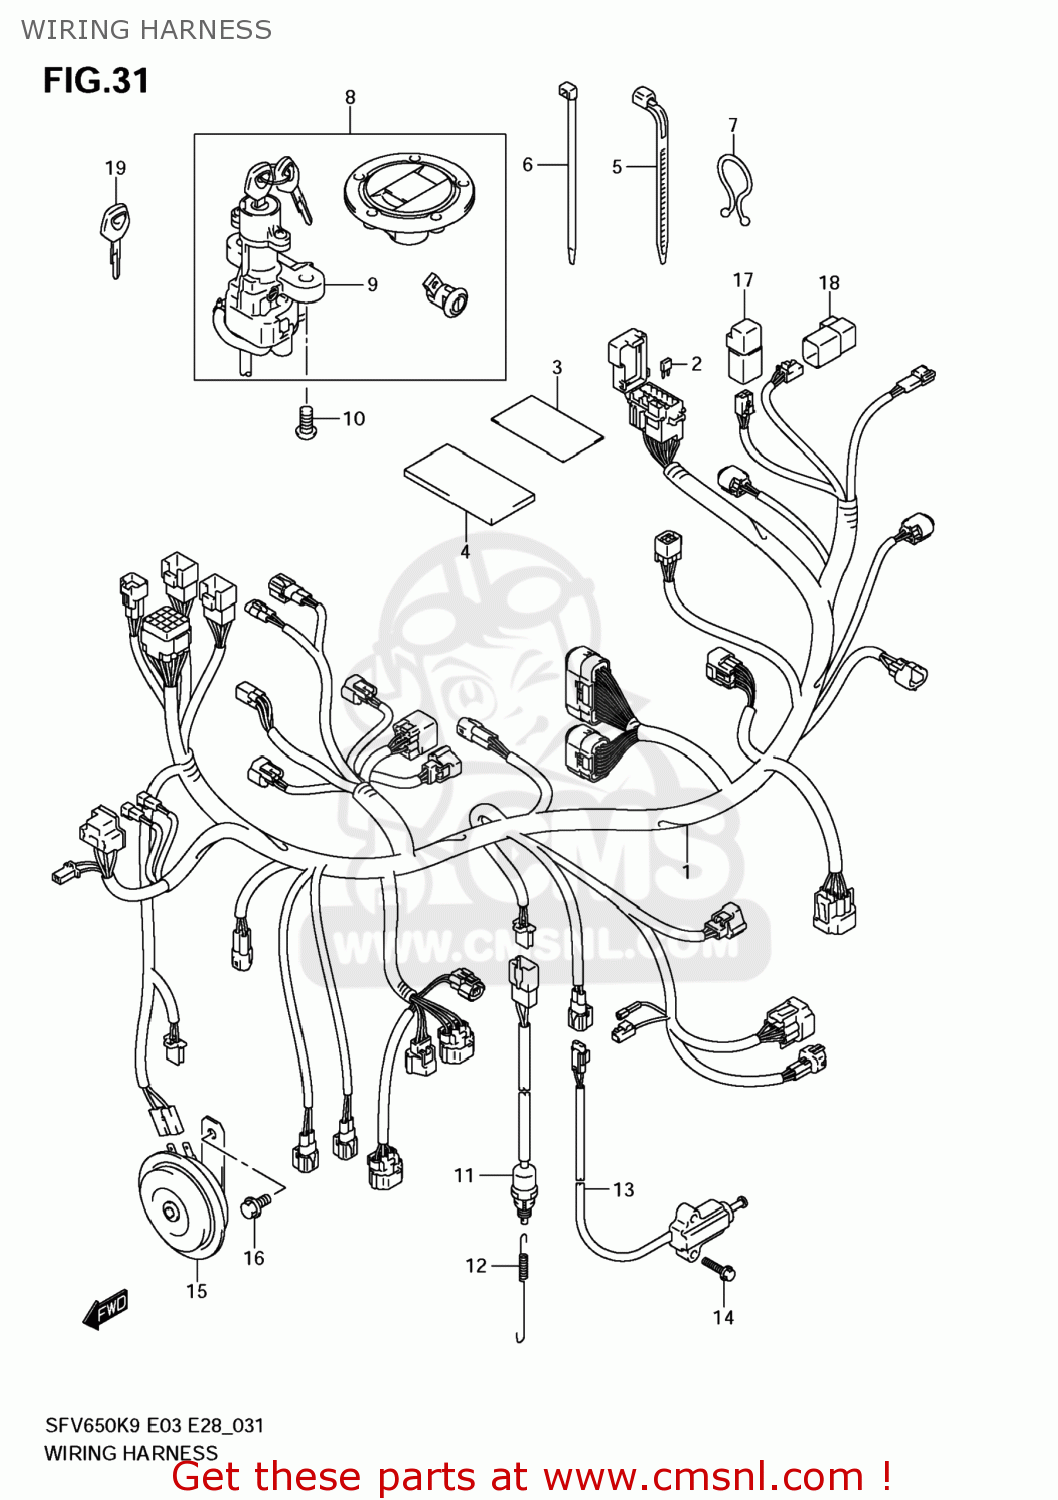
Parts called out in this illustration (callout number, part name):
1	HARNESS,WIRING
2	FUSE(10A)
3	TAPE,WIRING HARNESS(28X50X0.13
4	PROTECTOR(30X60X3)
5	CLAMP(L:95)
6	CLAMP(L:145)
7	CLIP(ID:11.5)
8	LOCK SET
9	LOCK ASSY,STEERING
10	BOLT(8X20)
11	SWITCH ASSY,ST
12	SPRING
13	SWITCH ASSY,SIDE STAND
14	BOLT
15	HORN ASSY
16	BOLT
17	RELAY ASSY
18	RELAY ASSY
19	KEY,BLANK
